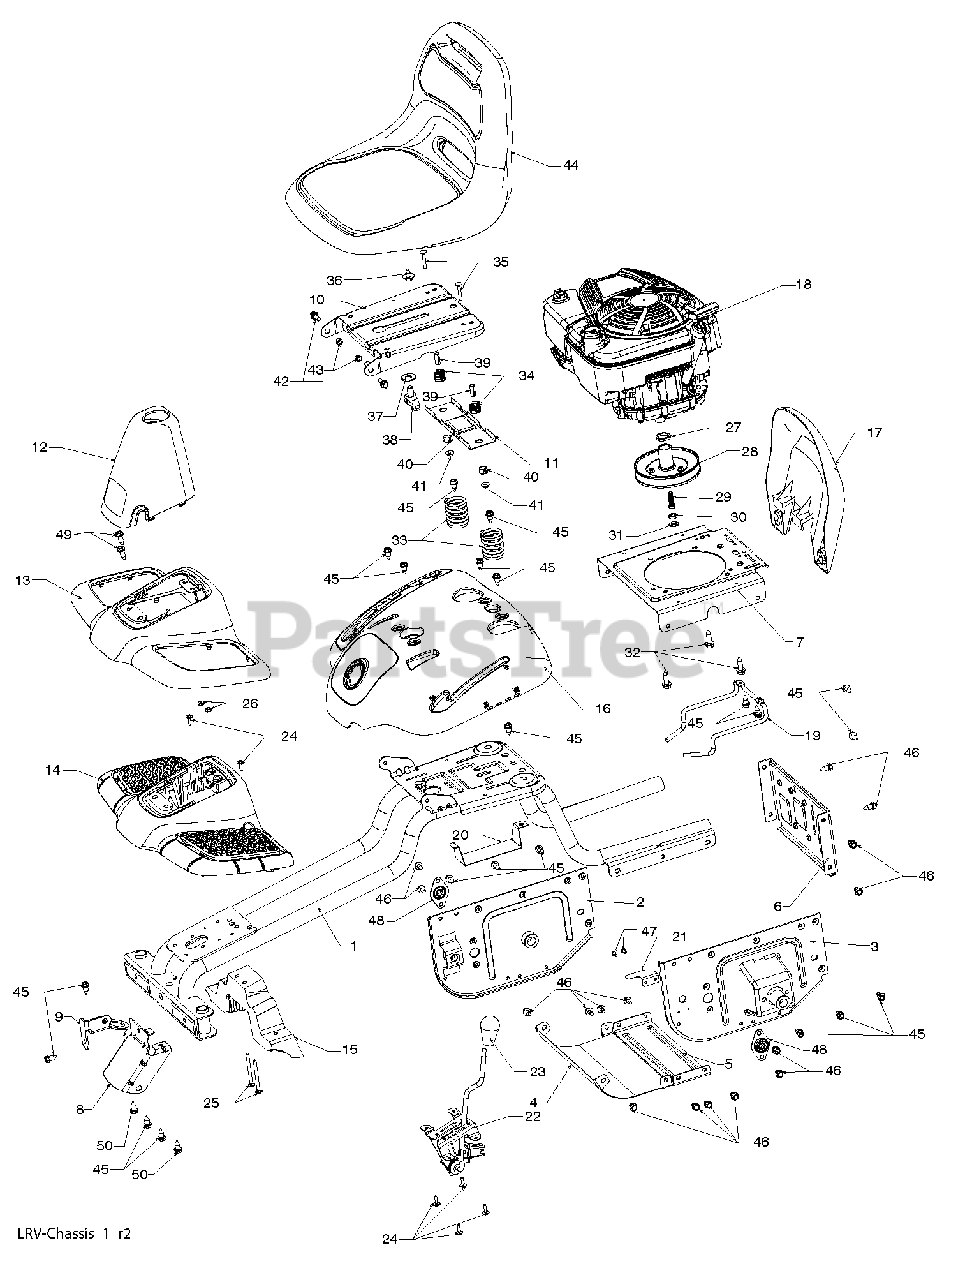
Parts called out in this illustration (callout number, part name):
1	WELDMENT, CHASSIS
2	SUPPORT, AXEL LH
3	SUPPORT, AXEL RH
4	SHIELD, TRANSAXLE FRONT
5	BRACE, AXLE CROSS
6	COVER, FRICTION DRIVE
7	PLATE, ENGINE
8	BRACKET, CHASSIS FRONT
9	BRACKET, STEERING SUPPORT
11	BRACKET, SWITCH MOUNTING
12	BOOT, DUST
13	COVER, FOOT REST
14	STRUCTURE, FOOT REST
15	SUPPORT, FOOT REST
16	FENDER, CONTROL
17	GUARD, ENGINE
18	ENGINE, (NON-CALIFORNIA) 12S907-1411-B1
18	ENGINE, (California) 121S07-1415-F1
18	ENGINE, (CANADA) 12S907-1463-B1
20	BRACKET, BATTERY
21	LEVER, SWITCH
22	DECK CLUTCH ASM
24	SCREW, NO. 10
25	BOLT, CARRIAGE 1/4-20 X 3
26	NUT, 1/4-20
27	SPACER, ENGINE
28	DISC, FRICTION ASM
29	BOLT, SCKT HD 3/8-24 X 1 .25
31	SPACER, NEUTRAL
32	BOLT, 3/8-16 X .280
33	SPRING, SEAT
35	BOLT, 1/4-20 X 1 1/2
36	BOLT, SHOULDER
37	WASHER, 17/32 X 1 3/16
40	BUSHING, NYLON SNAP
41	NUT, LOCK
42	BOLT, 5/16-18 SHOULDER
43	NUT, 5/16-18
44	SEAT
45	BOLT, 5/16-18 X 3/4
46	BOLT, 5/16-18 X 1/2
47	SCREW
48	BEARING, FLANGE, BALL
49	SCREW, 5/16-18 X1
50	Bolt, Shoulder, 5/16-18 x .561
